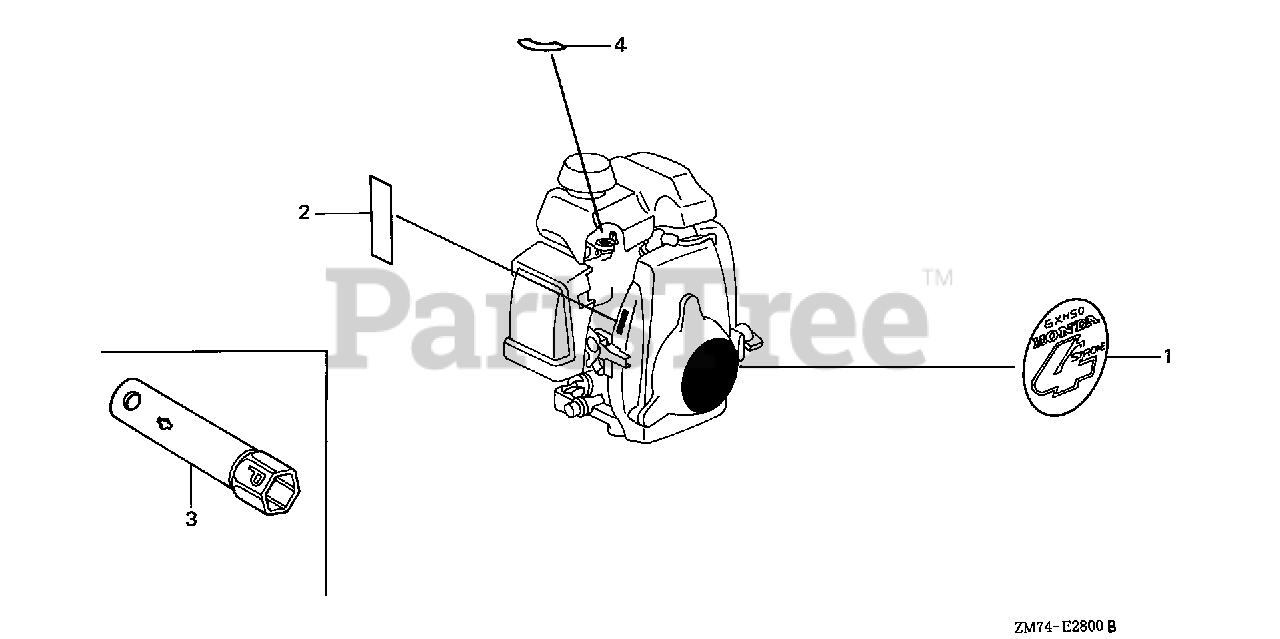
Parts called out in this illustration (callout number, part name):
1	EMBLEM
2	MARK, THROTTLE INDICATION
3	WRENCH, SPARK PLUG
4	MARK, COCK (EXTERNAL)
